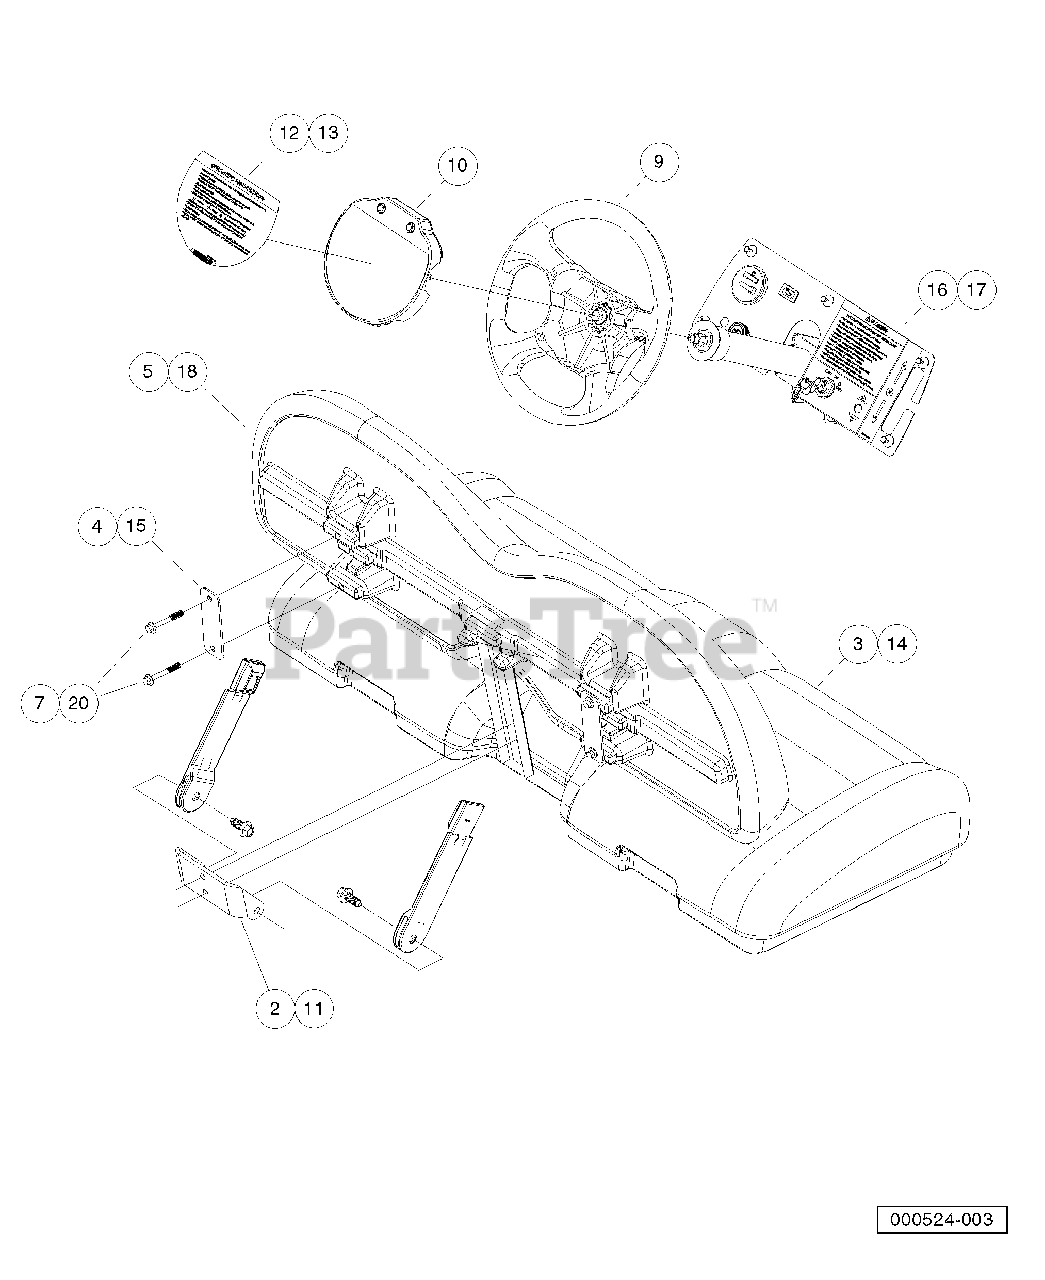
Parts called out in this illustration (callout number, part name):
1	Kit, Bench Seat, Seat Only
2	Bracket, Seat Belt, Bench
3	Asm, Seat Bottom, Bench, Gray
4	Bracket, Seat Back, AWD
5	Seat Back, Bench, Gray
6	Instructions, Bench Seat
7	Bolt Flg Blk, M8 X 55, Loctite
8	Kit, Bench Seat, Complete
9	Steering Wheel, Comfort Grip, Hex
10	Center, Plate, Steering Wheel
11	Bracket, Seat Belt, Bench
12	Decal, Oper Instr, Awd Se Dsl
13	Decal, Oper Instr, Awd Se Gas
14	Asm, Seat Bottom, Bench, Gray
15	Bracket, Seat Back, AWD
16	Decal, Warning, Iinstrument Panel, AWD Gas
17	Decal, Warning, Iinstrument Panel, AWD Diesel
18	Seat Back, Bench, Gray
19	Instructions, Bench Seat
20	Bolt Flg Blk, M8 X 55, Loctite
